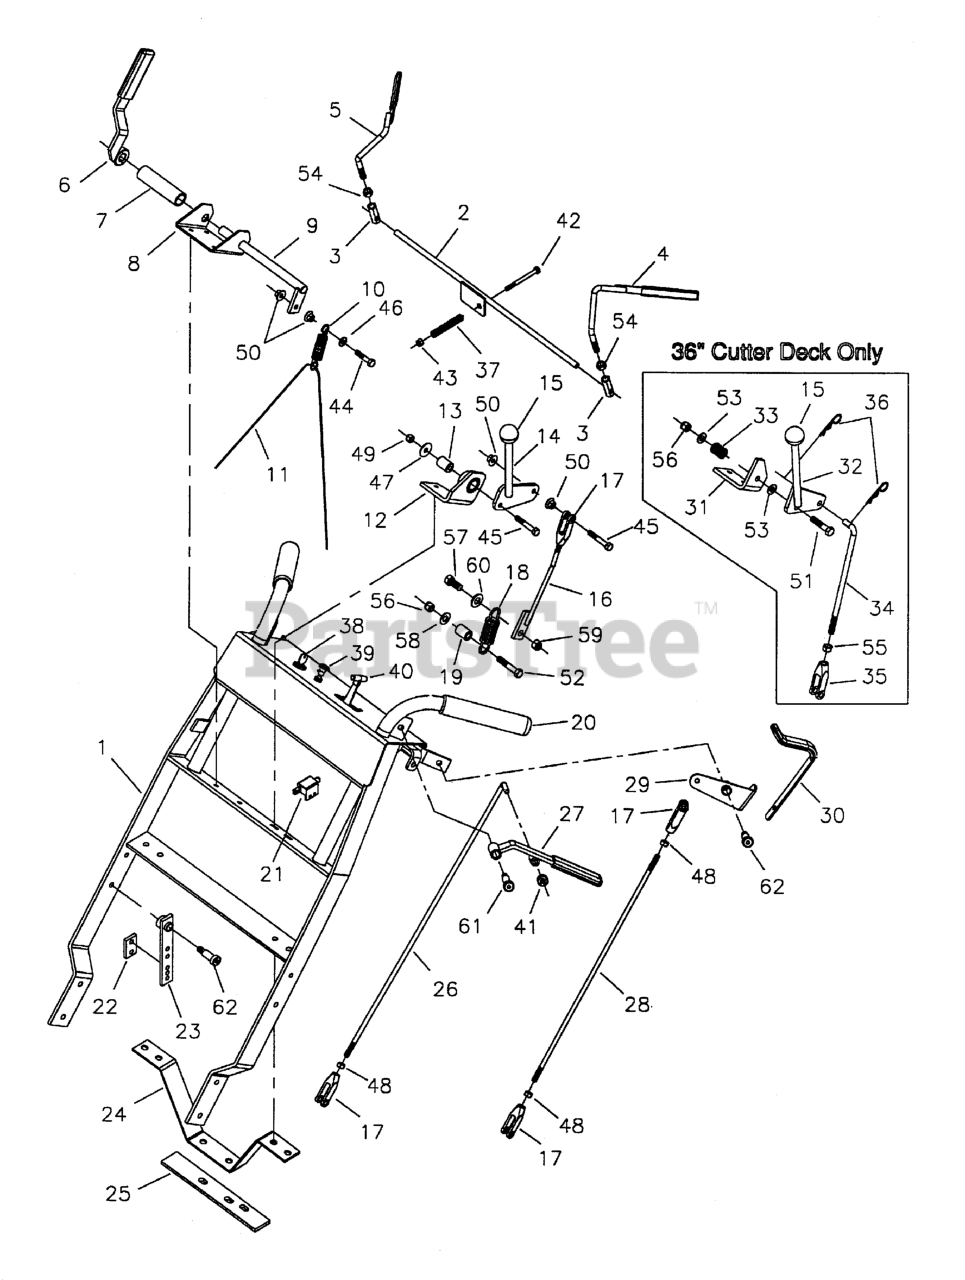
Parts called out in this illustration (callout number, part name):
1	Handle Bar Weldment
2	SWITCH ROD
3	HEX ADJUSTER
4	ASSM, OPERATOR PRESENCE, LH
5	ASSM, OPERATOR PRESENCE, RH
5	GRIP, Vinyl
6	PARKING BRAKE HANDLE
6	GRIP, FOAM, 1/4 X 1 X 4.1
7	3/4" PVC, 4" Long
8	PARKING BRAKE MOUNT
9	PARKING BRAKE SHAFT
10	SPRING, Extension
11	1/8" WIRE ROPE, 31-1/2" Long
12	Bracket, Blade Engage. W/ Bushing
12	BUSHING, Brass
13	SPACER, .32 x .75 x 1.06
14	Handle, Blade Engagement
15	KNOB
16	Linkage, Blade Engagement
17	CLEVIS, 5/16-24, Plastic
18	SPRING, Extension
19	Pivot, Spring
20	GRIP, Foam
21	SWITCH, Plunger, NO
22	CABLE CLAMP
23	BRAKE PIVOT
24	Support, Handle Bar
25	Support, Engine Deck
26	ROD, Brake Linkage
27	Handle, Brake w/Grip
27	GRIP, FOAM, 1/4 X 1 X 4.1
28	ROD, Thumb Control
29	PIVOT CONTROL WELDMENT - LH
29	PIVOT CONTROL WELDMENT - RH
30	THUMB CONTROL LEVER, Complete
30	GRIP, FOAM, 1/4 X 1 X 4.1
31	BRACKET, Shifter
32	LEVER, Blade Engagement
33	SPRING, Compression
34	ROD, Blade Engagement
35	CLEVIS, 3/8-24, Plastic
36	HAIRPIN CLIP
37	SPRING, Compression
38	SWITCH, Ignition
38	Ignition Key
39	CABLE, CHOKE CONTROL, 45
40	CABLE, Throttle, 31"
41	COLLAR, 5/16" Set
42	BOLT, 1/4-20 x 3
43	NUT, 1/4-20 HEX NYLON LOCK
44	BOLT, 5/16-18 x 1-1/2
45	BOLT, 5/16-18 X 2
46	WASHER, 5/16" SAE
47	WASHER, 5/16" Fender
48	NUT, 5/16-24 Hex
49	NUT, 5/16-18 Hex Nylon Lock
50	NUT, 5/16-18 HEX SERRATED FLANGE (LARGE)
51	BOLT, 3/8-16 X 1-3/4" GD5 CZ
52	BOLT, 3/8-16 X 2, GD5, CZ
53	WASHER, 3/8 SAE
54	NUT, 3/8-16 Hex
55	NUT, 3/8-24 Hex
56	NUT, 3/8-16 HEX NYLON LOCK
57	BOLT, 7-16-14 x 1
58	WASHER, 7/16" SAE
59	NUT, 7/16-14 Hex Nylon Lock
60	WASHER, 1/2 SAE
61	SHOULDER BOLT, 1/2 x 1-1/2
62	SHOULDER BOLT, 1/2 x 1
